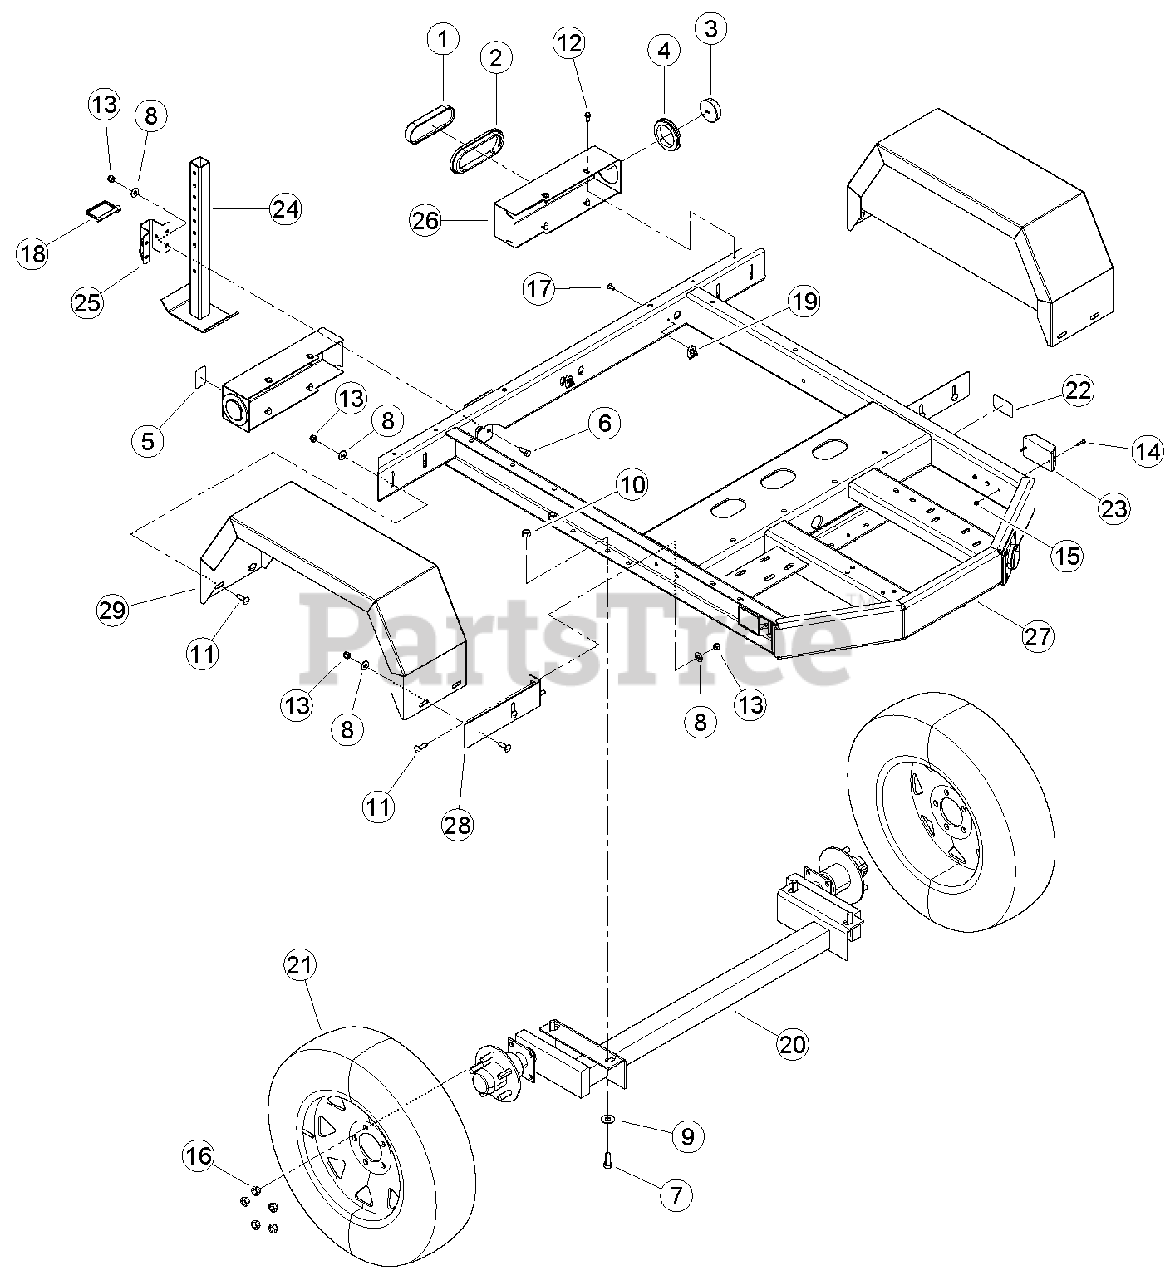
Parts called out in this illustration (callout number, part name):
1	TAIL LIGHT, OVAL RED
3	LIGHT, RED CLEARANCE
4	GROMMET, CLEARANCE LIGHT
5	REFLECTOR, WIDE ANGLE RED
6	BOLT, 3/8 X 1 HEX HD GR5 ZP
7	BOLT, 1/2 X 1-1/4 HHCS GR5 NC ZP
8	WASHER, 3/8 FLAT ZP
9	WASHER, 1/2 FLAT ZP
10	NUT, 1/2 CENTERLOCK GRB ZP
11	BOLT, 3/8 X 1 CRG GR5 NC ZP
12	SCREW, 11/32 X 7/8 HWH AB THREAD ZP
13	NUT, 3/8 NE NYLOCK ZP
14	MACH. SCREW,10-24 X 1 RND HD PHL ZP
15	NUT, 10/24 NYLOCK TYPE NM ZP
16	BOLT, 1/2-18 WHEEL LUG
17	RIVET, 1/4 X 3/4 AL BLIND DOME HEAD
18	PIN, 3/8 X 1-3/4 SNAP
19	CLAMP, CABLE MOUNT
20	AXLE, DURA-FLEX TORSION 1800
21	ASSY', TIRE AND WHEEL 14 IN.
22	DECAL, P205/75R14 LOAD RATING
23	LIGHT, AMBER SIDE MARKER
24	WELDMENT, REAR STABILIZER
25	GUIDE, TRAILER SUPPORT
26	BRACKET, TAIL LIGHT
27	WELDMENT, CHIPPER TRAILER
28	BRACKET, FENDER
29	WELDMENT, CHIPPER FENDER
